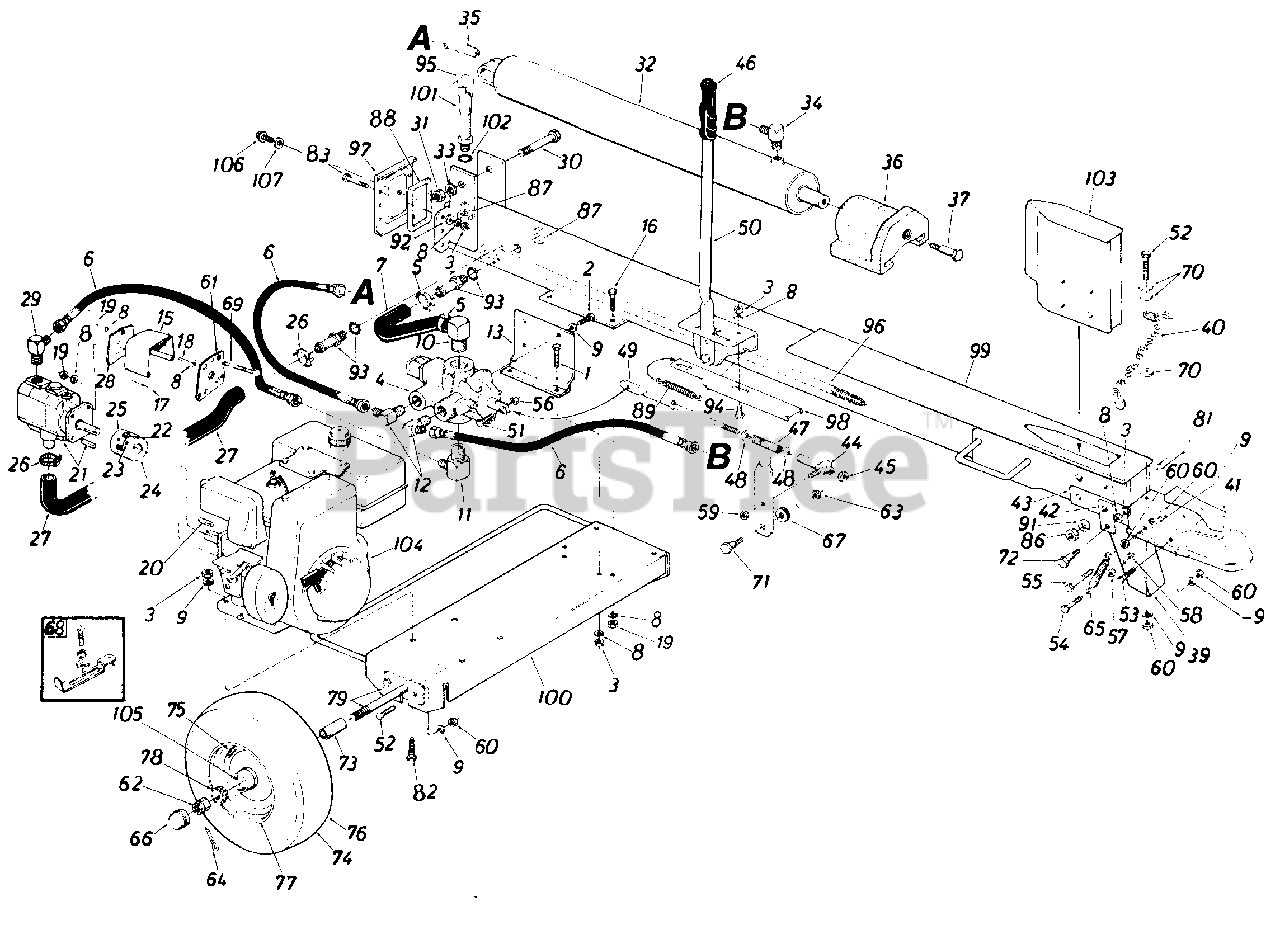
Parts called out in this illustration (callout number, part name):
1	Hex Bolt 5/16-18 x .75" Lg.*
2	Hex Bolt 3/8-16 x .50 Lg.*
3	Hex Nut 5/16-18 Thd.*
4	Control Valve 400
5	Hose Clamp 5/8"
6	High Pressure Hose Ass'y. .38" I.D.
7	Return Hose - Valve to Tank 3/4" I.D.
8	L.-Wash.5/16" I.D.*
9	L.-Wash. 3/8" I.D.*
10	Return Elbow
11	90ø Solid Male Adapter
12	90ø Solid Male Adapter
13	Valve Mtg. Plate
15	Coupling Shield
16	Hex Bolt 5/16-24 x 1.00" Lg.*
17	Hex Bolt 5/16-24 x .75" Lg.*
18	Hex Bolt 5/16-24 x .62" Lg.
19	Hex Nut 5/16-24 Thd.*
20	Sq. Key 3/16" x 2.25" Lg.
21	Pump with Woodruff Key
22	Spider L-0-90
23	Set Scr. 1/4-20x .25" Cup
24	Coupling Half .75" I.D.
25	Coupling Half .50" I.D.
26	Hose Clamp 5/8"
27	Suction Hose 1.0" Dia.
29	90ø Solid Male Adapter
30	Hex Bolt 3/4" x 4.0" Lg.
31	Hex Nut 3/4" Thd.
32	Hydraulic Cylinder 3-1/2" Dia.
33	L.-Wash. 3/4" I.D.*
34	High Pressure 90ø Elbow
35	45ø Male Adapter 3/4-16 MJ- 3/8-18 NP
36	Pusher Plate
37	Shoulder Bolt .62" Dia. x 4.75" Lg. (1/2-13 Thd.)
39	Flip Stand Bracket
40	Chain-Tow Hitch
41	Tow Hitch Ass'y. Comp.
42	Stand Pivot Bracket
43	Tow Hitch Brk't. 2 x 3/16 x 10.25" Lg.
44	Ferrule Assy.
45	Hex Cent. L.-Nut 3/8-24 Thd.
46	Grip-Black Vinyl
47	Compl'ession Spring
48	Special Washer .378 x 1.00" x .125 Thd.*
49	Engagement Rod 3/8" Dia. x 9.0 ' Lg.
50	Engagement Handle
51	Hex Bolt 1/4-20 x 1.75" Lg.
52	Hex Bolt 3/8-24 x 1.25" Lg.*
53	Hex Bolt 3/8-24 x .75" Lg.*
54	Hex Bolt 1/4-28 x 1.00" Lg.*
55	Hex Bolt 3/8-24 x 1.75" Lg. (Grade 5)
56	Hex Patch L.-Nut 1/4-20 Lg.*
57	Hex Cent. L.-Nut 1/4-28 Thd.
58	Hex Nut 1/4-28 Thd.
59	Hex Cent. L.-Nut 5/16-18 Thd.
60	Hex Nut 3/8-24 Thd.*
62	Hex Castle Nut 3/4-16 Thd.
63	Hex L.-Nut 3/8-16 Thd.
64	Cotter Pin 5/32" Dia. x 1.25" Lg.*
65	Extension Spring .50" O.D. 3.97" Lg.
66	Hub Cap
67	Rubber Washer
68	Throttle Control
69	Hex Bolt 5/16-24 x 4.0" Lg.*
70	Fl.-Wash. .375" I.D. x .870" O.D. x .090
71	Shoulder Bolt .498" Dia. x .340" Lg.
72	Shoulder Bolt .437" Dia. x .268" Lg.
73	Spacer .75" I.D. x 1.12" O.D. x 1.56" Lg.
75	Air Valve- Tubeless
76	Tire Only 16.0 x 4.0-2 Ply
78	Roller Rearing 3/4" I.D.
79	Axle Ass'y. .75" Dia. x 36.25" Lg
81	Hex Bolt 5/8-18 x 3.50" Lg.*
82	Hex Bolt 5/16-24 x 1.75 Lg.*
83	Hex Bolt 5/16-18 x 1.50" Lg.*
86	Hex Nut 5/1-18 Thd.*
87	Hex Nut 11/16-12 Thd.
88	Gasket 2.62 x 5.12
89	Extension Spring .50" O.D. x 4.25" Lg .
91	L.-Wash. 5/8" 1.D.*
92	Fl.-Wash. 34" 1.D. x .68" O.D. x .062 Thk.
93	Adapter 1.0" Tube 11/16-1 " O " -Ring
94	Shoulder Bolt .437" Dia. x .180" Lg.
95	Breather Cap
96	Strainer Tube Ass'y.
97	End Plate
98	Engagement Brk't. 1.39 x 11.75" Lg.
99	Complete Oil Tank Ass'y.
100	Engine Frame Ass'y.
101	Filler Tube Ass'y.
102	"O"-Ring92" I.D. x 1.16" O.D. x .116 Dia.
103	Wedge Ass'y.
104	5 H.P. Engine
105	Bearing Seal
106	Hex Hd. Tap Scr. 5/16"
107	Gasket
